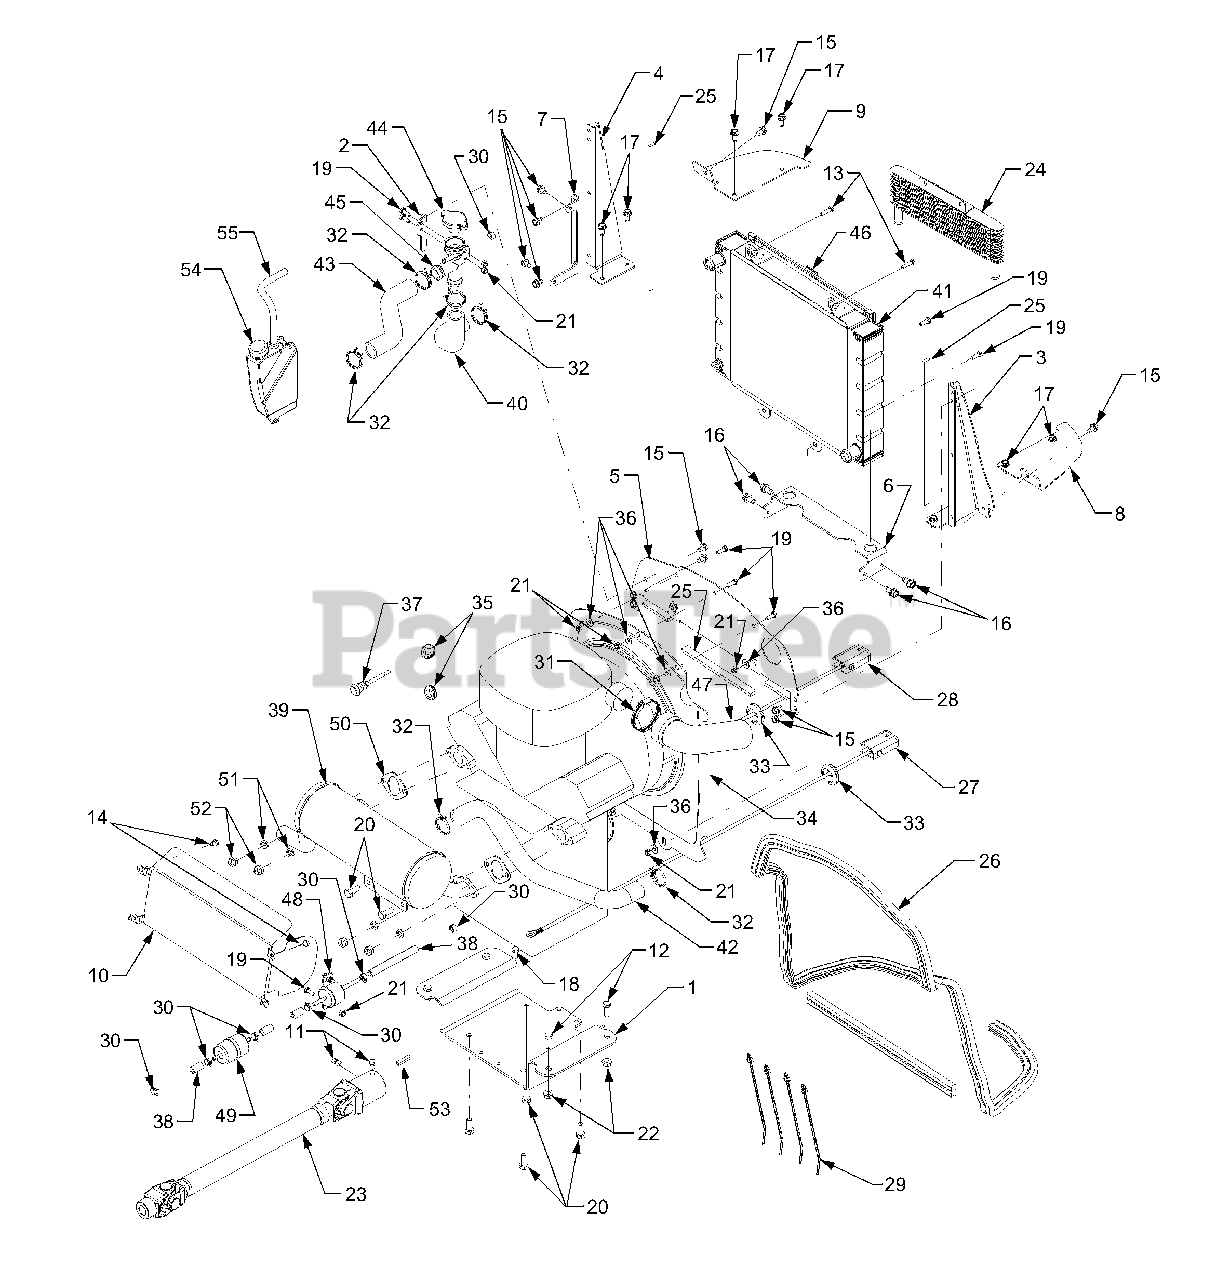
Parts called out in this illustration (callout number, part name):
1	Plate, Engine Mtg.
2	Bracket, Filler Neck
3	Bracket, Radiator Mtg. RH
4	Bracket, Radiator Mtg. LH
5	Plate, Radiator Baffle
6	Bracket, Radiator Mtg.
7	Bracket, Ovrflw Bottle Mtg.
8	Plate, Baffle RH
9	Plate, Baffle LH
10	Shield, Heat
11	Screw, Square Hd. Set, 3/8-16
12	Screw, Hex Cap, 3/8-16 x 1.0 GR5
13	Screw, Hex Cap, 1/4-20 x 1.0 GR5
14	Screw, Hex Wash Hd Tapp 1/4-20 x .5
15	Screw, Hex Wash Hd Tapp 5/16-18 x .5
16	Screw, Hex Wash Hd Tapp 3/8-16 x .75
17	Screw, Hex Wash Hd Tapp 5/16-18 x .75
18	Screw, Hex Cap, M8-20 x 16
19	Screw, Hex Cap, 1/4-20 x .75 GR5
20	Screw, Hex Cap, M10 x 1.5 x 25
21	Nut, Hex Nylon Insert Lock 1/4-20 GR8
22	Nut, Hx Flnge Lock, 3/8-16
23	Shaft, Drive
24	Cooler, Oil
25	Tape, Foam, .625 wide
26	Seal, Heat Baffle
27	Wire, Battery Neg.
28	Wire, Battery Pos.
29	Tie, Cable - Push Mount
30	Clamp, Hose
31	Clamp, Hose - Adjustable
32	Clamp, Hose
34	Shroud, Fan
36	Washer, Flat, .28 x .74 x .063
37	Cable, Choke Control
38	Fuel Line 5/16 ID
40	Hose, Filler to Radiator
42	Hose, Lower Radiator
43	Hose, Engine to Filler Neck
44	Filler Neck, Remote Radiator
45	Cap, Remote Filler
46	Screen, Radiator
47	Hose, Intake Air
49	Filter, Fuel
50	Gasket, Exhaust
51	Washer, Spring
53	Key, Crankshaft
54	Bottle, Over Flow
